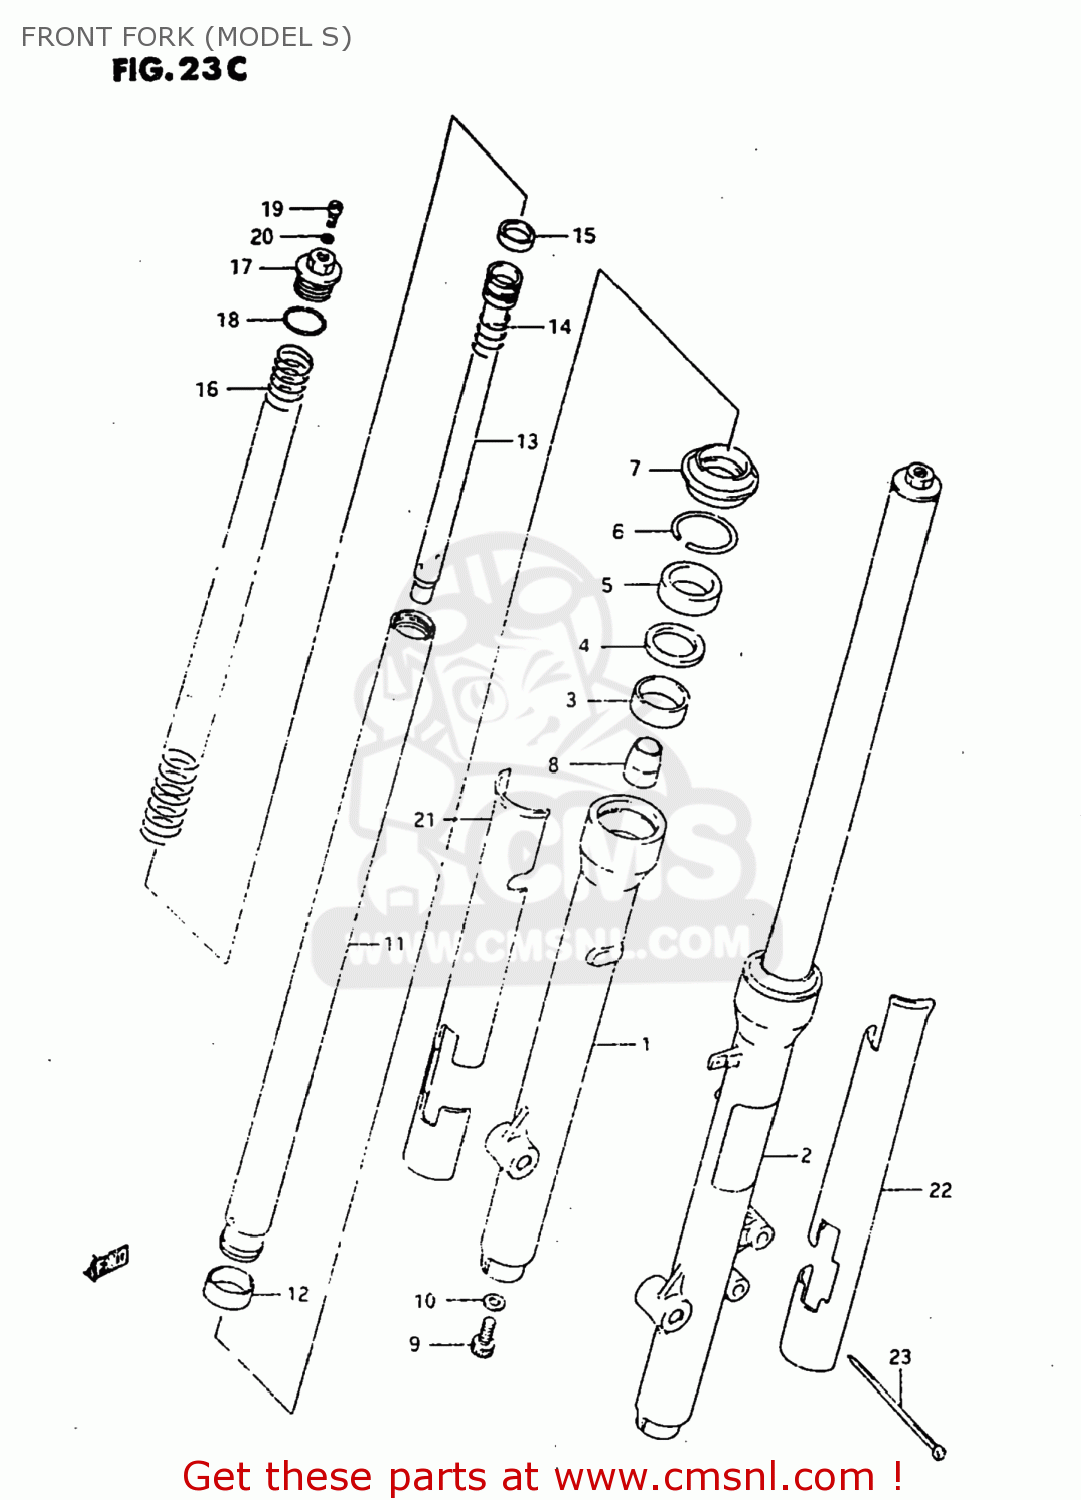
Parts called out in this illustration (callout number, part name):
1	TUBE,OUTER,R
2	TUBE,OUTER,L
3	BUSH,GUIDE
4	SPACER,SEAL
5	SEAL,OIL 35X48X11
6	RING,OIL SEAL STOPPER
7	SEAL,DUST
8	PIECE,OIL LOCK
9	BOLT(8X27)
10	GASKET (NAS)
11	TUBE,INNER
12	PISTON
13	SEAT,UNDER
14	SPRING,REBOUND
15	RING,PISTON
16	SPRING,UNDER
17	BOLT,FORK
18	O RING
19	BOLT,PLUG
20	O RING
21	PROTECTOR,FR FORK,R
22	PROTECTOR,FR FORK,L
23	CLAMP
